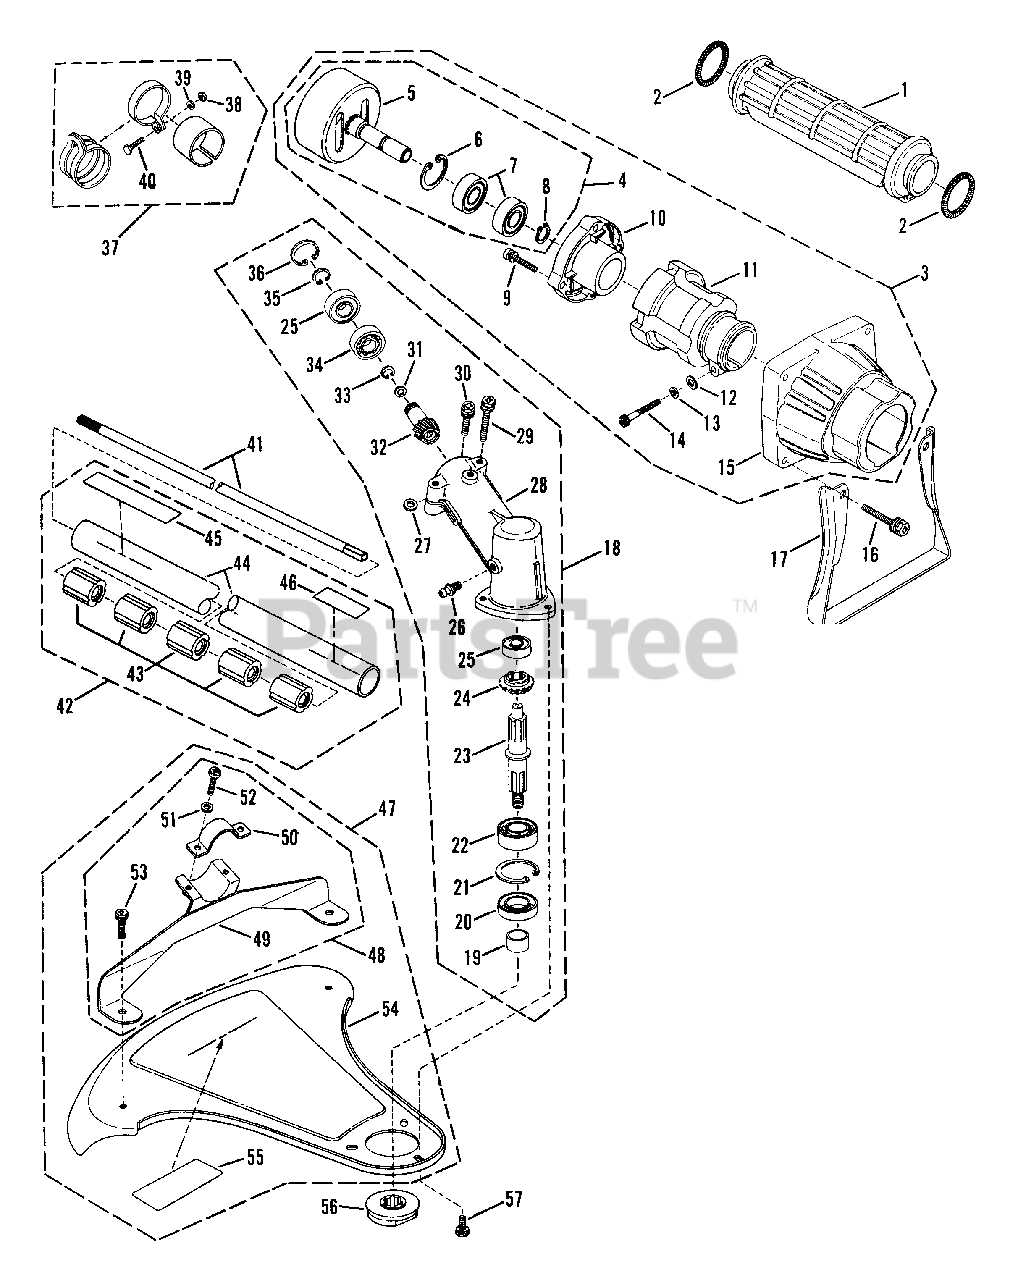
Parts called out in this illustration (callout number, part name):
1	GRIP, Main Shaft
2	SPRING, Grip
3	CLUTCH CASE ASSM'Y.
4	CLUTCH DRUM ASSM'Y.
5	DRUM, Clutch
6	SNAP RING, 26mm
7	BEARING
8	SNAP RING, 10mm
9	SCREW, M5 x 20mm
10	CLUTCH BEARING COVER
11	INSERT RING
12	WASHER, Flat, M5
13	LOCKWASHER, M5
14	SCREW, M5 x 25mm, Socket
15	CLUTCH CASE
16	BOLT, M6 x 28mm Hex Hd.
17	STAND
18	GEAR HEAD ASSM'Y.
19	SPLINE SLEEVE
20	SEAL, Oil
21	SNAP RING, 35mm
22	BEARING
23	SPLINE SHAFT
24	BEVEL GEAR
25	BEARING
26	FITTING, Lube
28	GEAR CASE
29	BOLT, M5 x 25mm Hex Hd.
30	BOLT, M5 x 12mm Hex Hd.
31	WASHER, Flat
32	BEVEL PINION
33	SNAP RING, 10mm
34	BEARING
35	SNAP RING, 10mm
36	SNAP RING, 26mm
37	HANGER, Band Assm'y.
38	NUT, M5 Hex
39	LOCKWASHER, M5
40	BOLT, M5 x 12mm Hex Hd.
41	SHAFT, Main (60.878" x .2756", .1969" Square End x .7874", .8465" Splined End
42	ASSEMBLY, Tubing & Bushing's
43	BUSHING
45	DECAL-SNAPPER
46	DECAL-WARNING (Eye Protection)
47	SHIELD-BRACE ASSM'Y.
48	BRACE ASSM'Y., Shield
49	BRACE, Shield
50	BAND, Shield Brace
51	WASHER, Flat
52	SCREW, M6 x 20mm
53	BOLT, M6 x 12mm Hex Hd.
54	SHIELD
55	DECAL-WARNING, Shield
56	HOLDER
57	BOLT, M5 x 10mm, Hex Hd.
